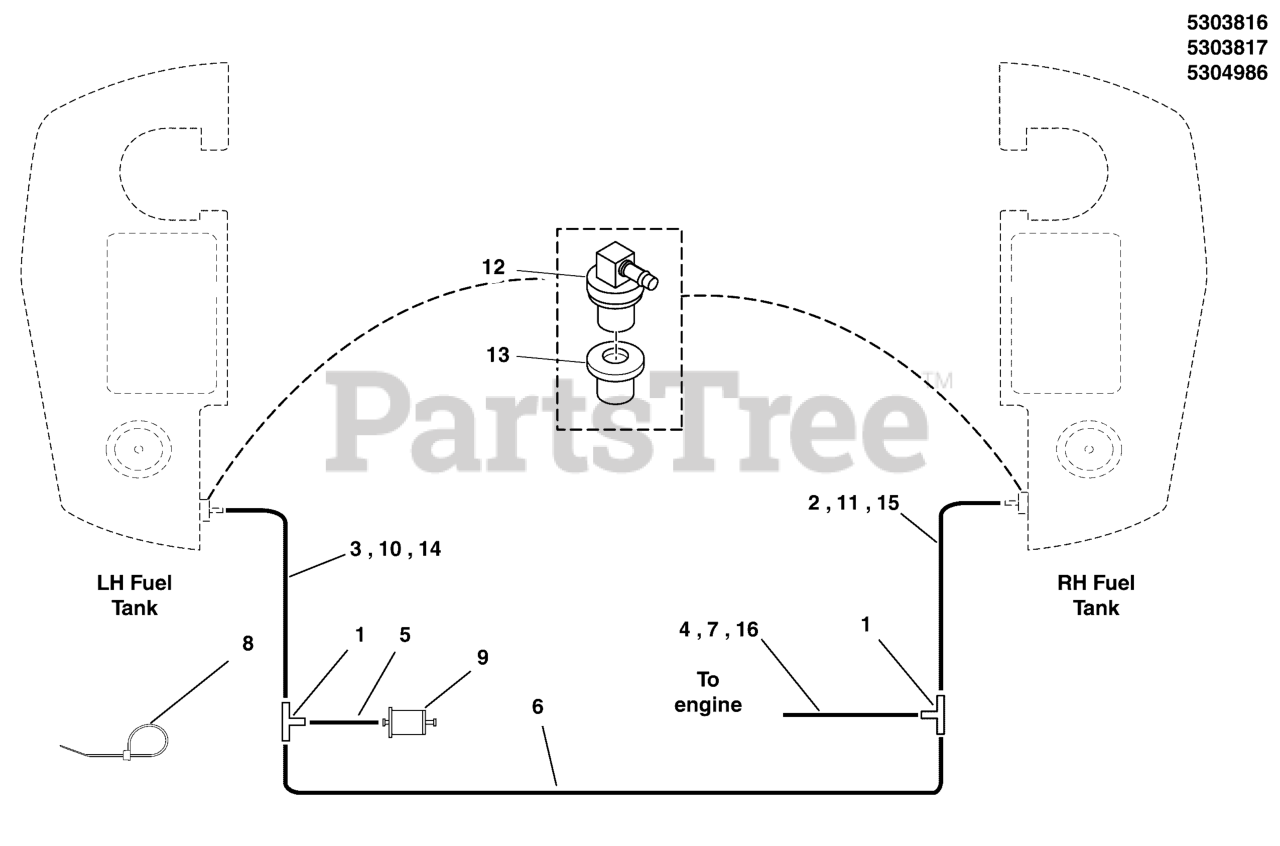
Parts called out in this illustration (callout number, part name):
1	FITTING, 3/16" TEE, BARB TYPE, HDPE
2	HOSE, VAPOR, 5MM ID, 16.50 LG
3	HOSE, VAPOR, 5MM ID, 33.00 LG
4	HOSE, VAPOR, 5MM ID, 8.00 LG
5	HOSE, VAPOR, 5MM ID, 2.00 LG
6	HOSE, VAPOR, 5MM ID, 15.00 LG
7	HOSE, VAPOR, 5MM ID, 18.00 LG
8	TIE, SELF-LOCKING, 6"
9	FILTER, FUEL
10	HOSE, VAPOR, 5MM ID, 16.50 LG
11	HOSE, VAPOR, 5MM ID, 33.00 LG
12	REMOTE VENT ASSEMBLY
13	GROMMET (SV)
14	HOSE, VAPOR, 5MM ID, 34.00 LG
15	HOSE-VAPOR
16	HOSE, VAPOR, 5MM ID, 26.00 LG
